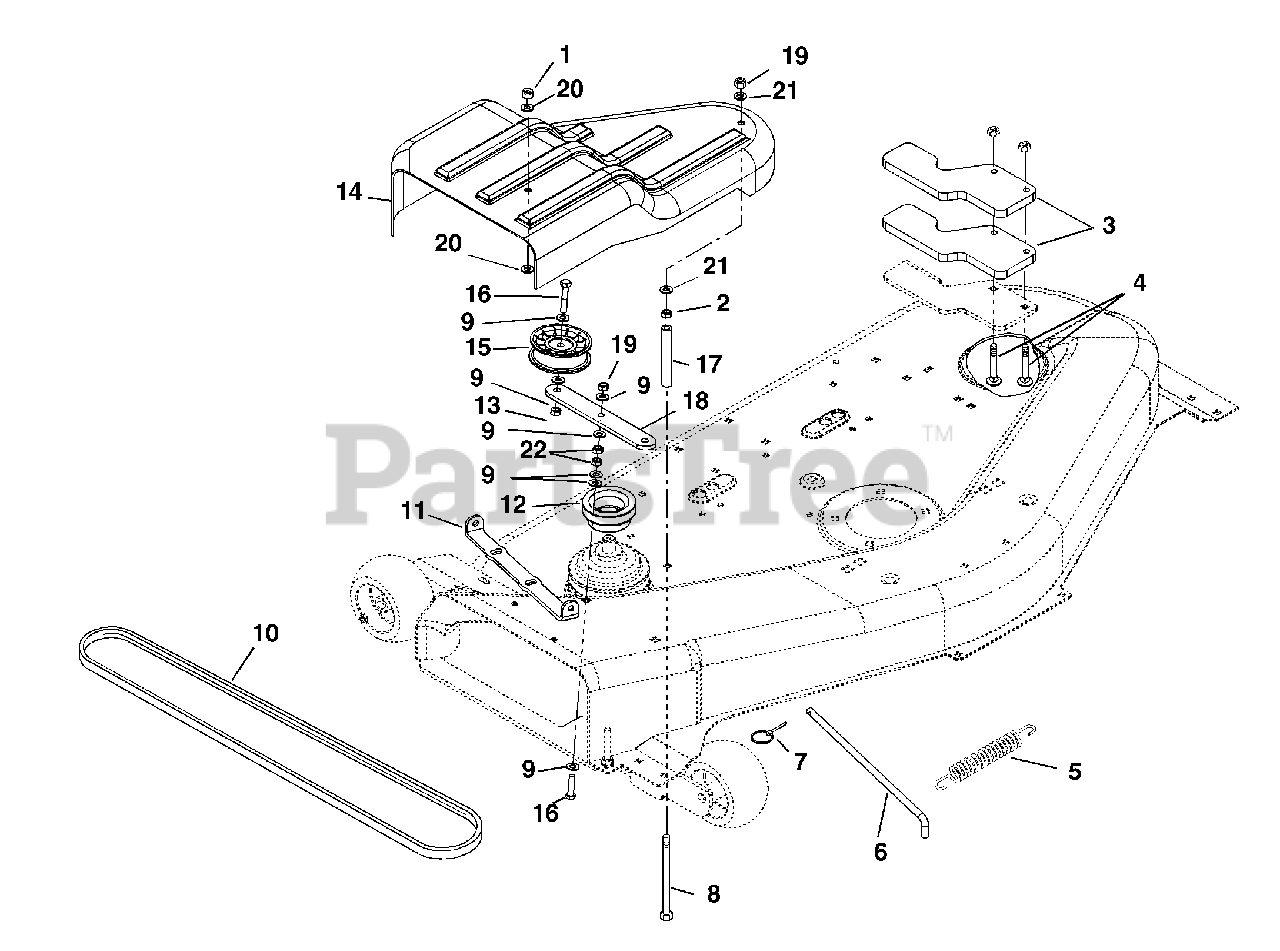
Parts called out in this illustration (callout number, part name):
1	@NUT-LK-NYL .250-20 YWZC
2	@NUT-LK-CTR .31-18 YWZC
3	COUNTERWEIGHT
4	@BLT-RDHDSQNK .31-18X1.75 G5YZ
5	SG-TENS .069X.62X3.50 WLD20
6	ROD-MOUNTING
7	PIN-KLIK 1.000X.188X1.25 YWZC
8	@BLT-HEX .31-18X5.50 GR5 YWZC
9	@WSHR-FL-STL.344X.688X.065YWZC
10	V-BELT, HA-RAW EDGE
11	BRACKET-CHUTE PIVOT
12	PULLEY-DRIVER 3.00"
13	@NUT-SPNLK-FLG .312-18 YWZC
14	COVER-GRASS PUMP BELTS
15	IDLER-FLAT 3.00X.38
16	@BLT-HEX .31-18X1.75 GR5 YWZC
17	SPACER .334X.500X4.625
18	BRACKET-TENSION ARM
19	@NUT-LK-NYL .312-18 YWZC
20	WSHR-FL-STL .281X1.000X.063
21	WSHR-FL-STL .347X1.254X.048YWZ
22	NUT- JAM .312-18 YWZC
